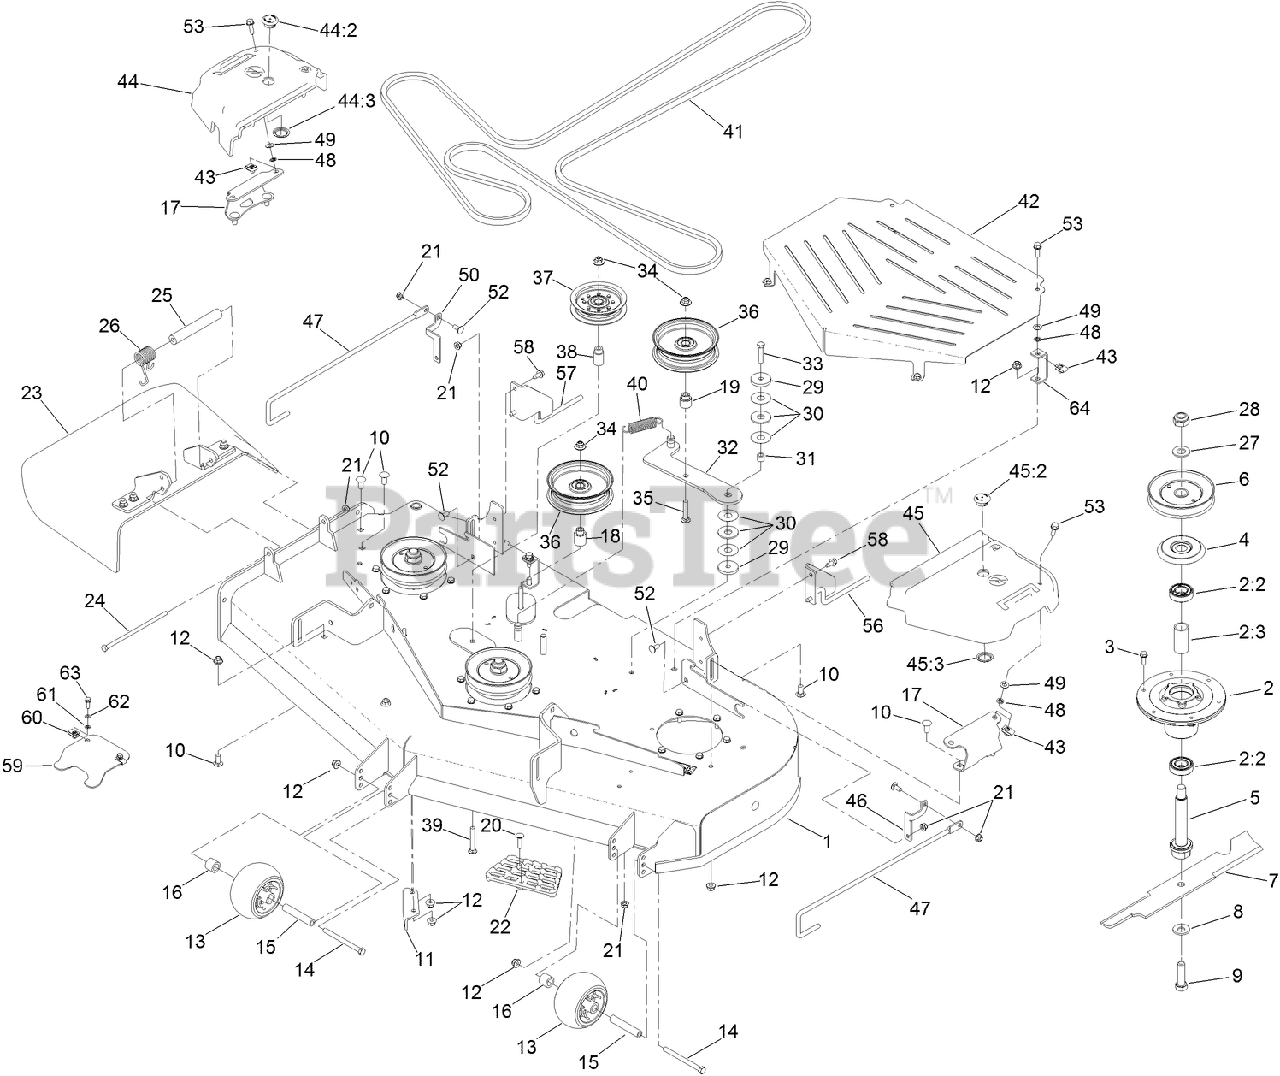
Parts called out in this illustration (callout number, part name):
1	DECK DECAL ASM
2	SPINDLE ASM
2:2	BEARING-BALL
2:3	SPACER-BEARING
3	SCREW-TAPTITE
4	SHIELD-BEARING
5	SHAFT-SPINDLE
6	PULLEY
7	BLADE-ROTARY, 18.0IN (HI FLOW)
8	WASHER-BELLEVILLE
9	SCREW-BLADE
10	SCREW-CARR
11	BAFFLE-DISCHARGE
12	NUT-HF, NI
13	ROLLER-SCALP, ANTI
14	SCREW-HH
15	TUBE-SPANNER
16	TUBE-SPACER
17	BRACKET-COVER, BELT
18	BUSHING-IDLER
19	BUSHING-IDLER
20	SCREW-CARR
21	NUT-HF, NI
22	STEP-DECK
23	DEFLECTOR ASM
24	SCREW-HH
25	SPACER
26	SPRING-TORSION
27	WASHER
28	NUT-LOCK, NI
29	WASHER-PLAIN
30	WASHER-FRICTION, COMPOSITE
31	BUSHING-LEVER, LIFT
32	ARM-IDLER
33	SCREW-HH
34	NUT-FLANGE, NI
35	SCREW-CARR
36	IDLER-PULLEY, FLAT
37	PULLEY-IDLER
38	BUSHING-IDLER
39	SCREW-CARR
40	SPRING-EXTENSION
41	BELT-DRIVE, DECK
42	GUARD-BELT, CENTER
43	NUT-U
44	RH BELT COVER ASM
44:3	RING-RETAINING
45	LH BELT COVER ASM
45:3	RING-RETAINING
46	BRACKET-MOUNT, REAR (LH)
47	ROD-SUPPORT, LOWER
48	NUT-PUSH
49	WASHER-THRUST
50	BRACKET-MOUNT, REAR (RH)
52	SCREW-CARR
53	SCREW-HHF
56	SUPPORT-LOWER, LH
57	SUPPORT-LOWER, RH
58	SCREW-HWHTF
59	PLATE-CLAMP, FOOTPAN
61	NUT-RETAINER
62	WASHER-FLAT
63	SCREW-HHF
64	BRACKET-GUARD
